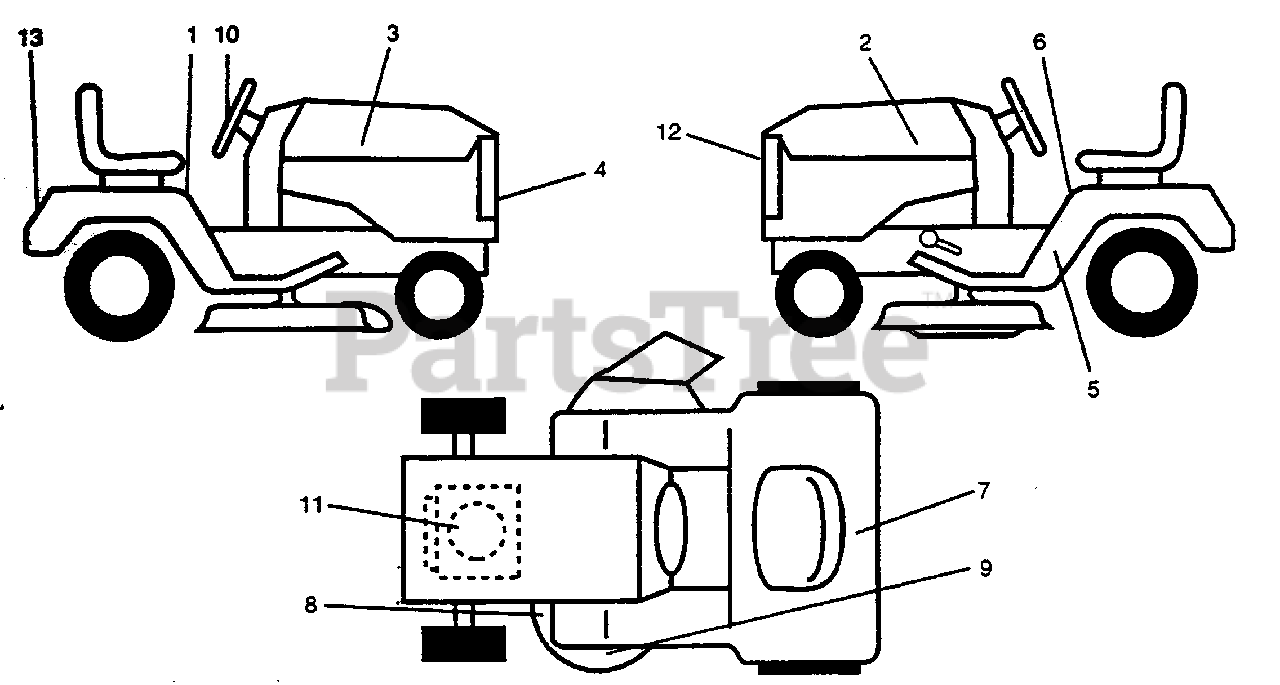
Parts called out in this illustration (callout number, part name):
1	Decal, Operating Instruction (AYP part number)
2	Decal, Hood, L.H. (AYP part number)
3	Decal, Hood, R.H. (AYP part number)
4	Decal, Logo, Grill
5	Decal, Mower Deck Height Indicator (AYP part number)
6	Decal, Caution (AYP part number)
7	Decal, Caution, Battery (AYP part number)
8	Decal, V-Belt Schematic (AYP part number)
9	Decal, Enviro-Deck (AYP part number)
10	Decal, Steering Wheel Insert (AYP part number)
11	Decal, Engine (AYP part number)
12	Decal, Lightbox, Lower (AYP part number)
13	Decal, Fender (AYP part number)
